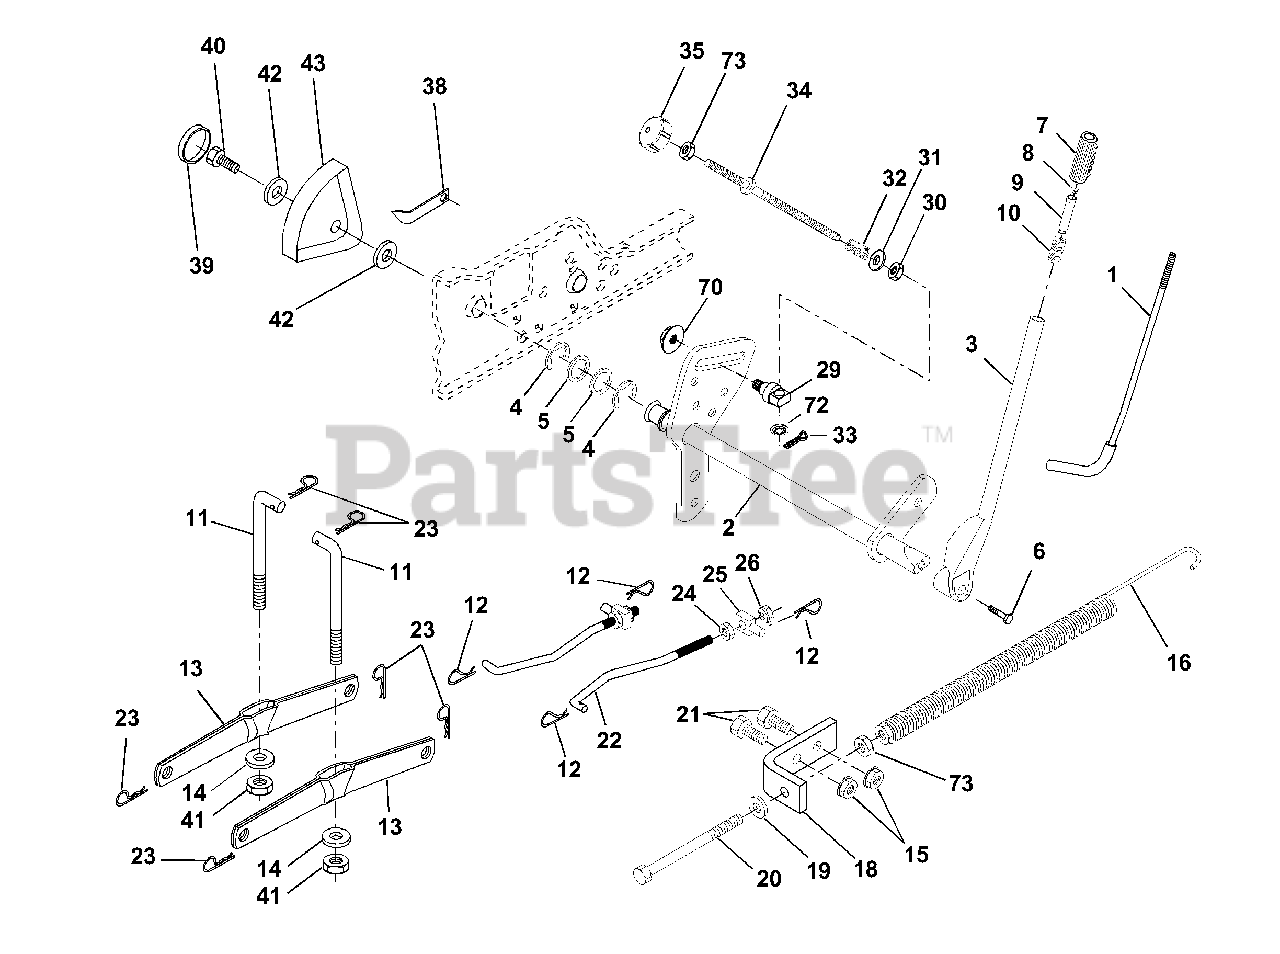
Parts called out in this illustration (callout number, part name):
1	Rod Asm., Lever
2	Shaft Asm., Lift Vgt
3	Lever Asm., Lift Rh
4	E-Ring Truarc #5133-87
5	Washer 29/32 x 1-1/4 x 16 Ga.
6	Bolt, Fin Hex 3/8-16 x 1-1/2
7	Grip, Handle Fluted
8	Button, Plunger
9	Plunger, Lever Lift
10	Spring 2-1/8"
11	Link Lift
12	Retainer, Spring
13	Arm, Suspension Vgt
14	Bearing Pivot Lift Tapered
15	Nut, Crownlock 3/8-16 Unc
16	Spring Asm., Assist Lift
17	Nut, Hex Jam 3/8-16 Unc
18	Bracket, Spring Assist
19	Washer 13/32 x 13/16 x 16 Ga.
20	Bolt, Adjust Spring Assist
21	Bolt, Fin Hex 3/8-16 x 1
22	Link, Front
23	Retainer, Spring
24	Nut, Jam Hex 1/2-13 Unc
25	Trunnion
26	Nut, Crownlock 1/2-13 Unc
29	Trunnion Inf. Height
30	Nut, Special
31	Washer 13/32 x 5/8 x 16 Ga.
32	Spring, Compression Inf Hgt
33	Pin, Cotter 3/32 x 1/2
34	Rod, Adj Lift
35	Knob, Inf 3/8-16 Unc
38	Pointer, Height Indicator
39	Plug, Hole
40	Screw 5/16-18 x 3/4
41	Nut, Crownlock 3/8-24
42	Washer 11/32 x 1-1/2 x 10 Ga.
43	Scale, Indicator Height
70	Nut, Hexflange Lock
72	Nut, Push Phos & Oil
73	Nut Hex Jam 3/8-16 Unc
